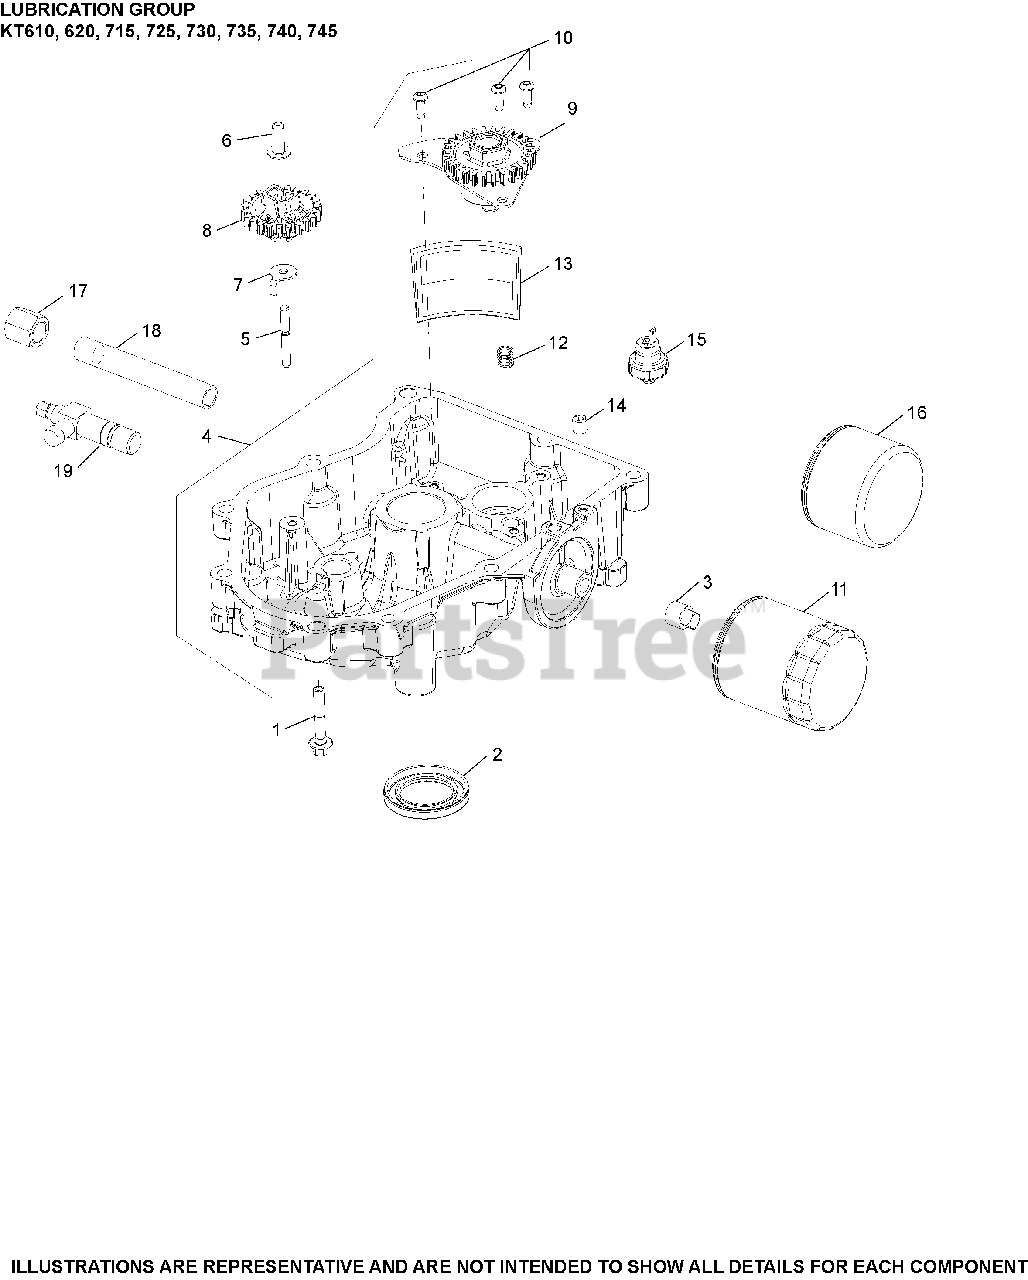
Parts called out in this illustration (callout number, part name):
1	SCREW, FLG M8X1.25X45
2	SEAL, OIL
3	PLUG, SQ HD PIPE 3/8"
4	PAN ASSEMBLY, OIL
5	SHAFT, GOVERNOR GEAR
6	PIN, GOVERNOR REGULATING
7	TAB, LOCKING
8	KIT, GOVERNOR GEAR
9	PUMP ASSEMBLY, OIL
10	SCREW, BUTTON HEAD
11	OIL FILTER
12	SPRING, COMPRESSION
13	SCREEN, OIL
15	SENSOR, OIL PSI
